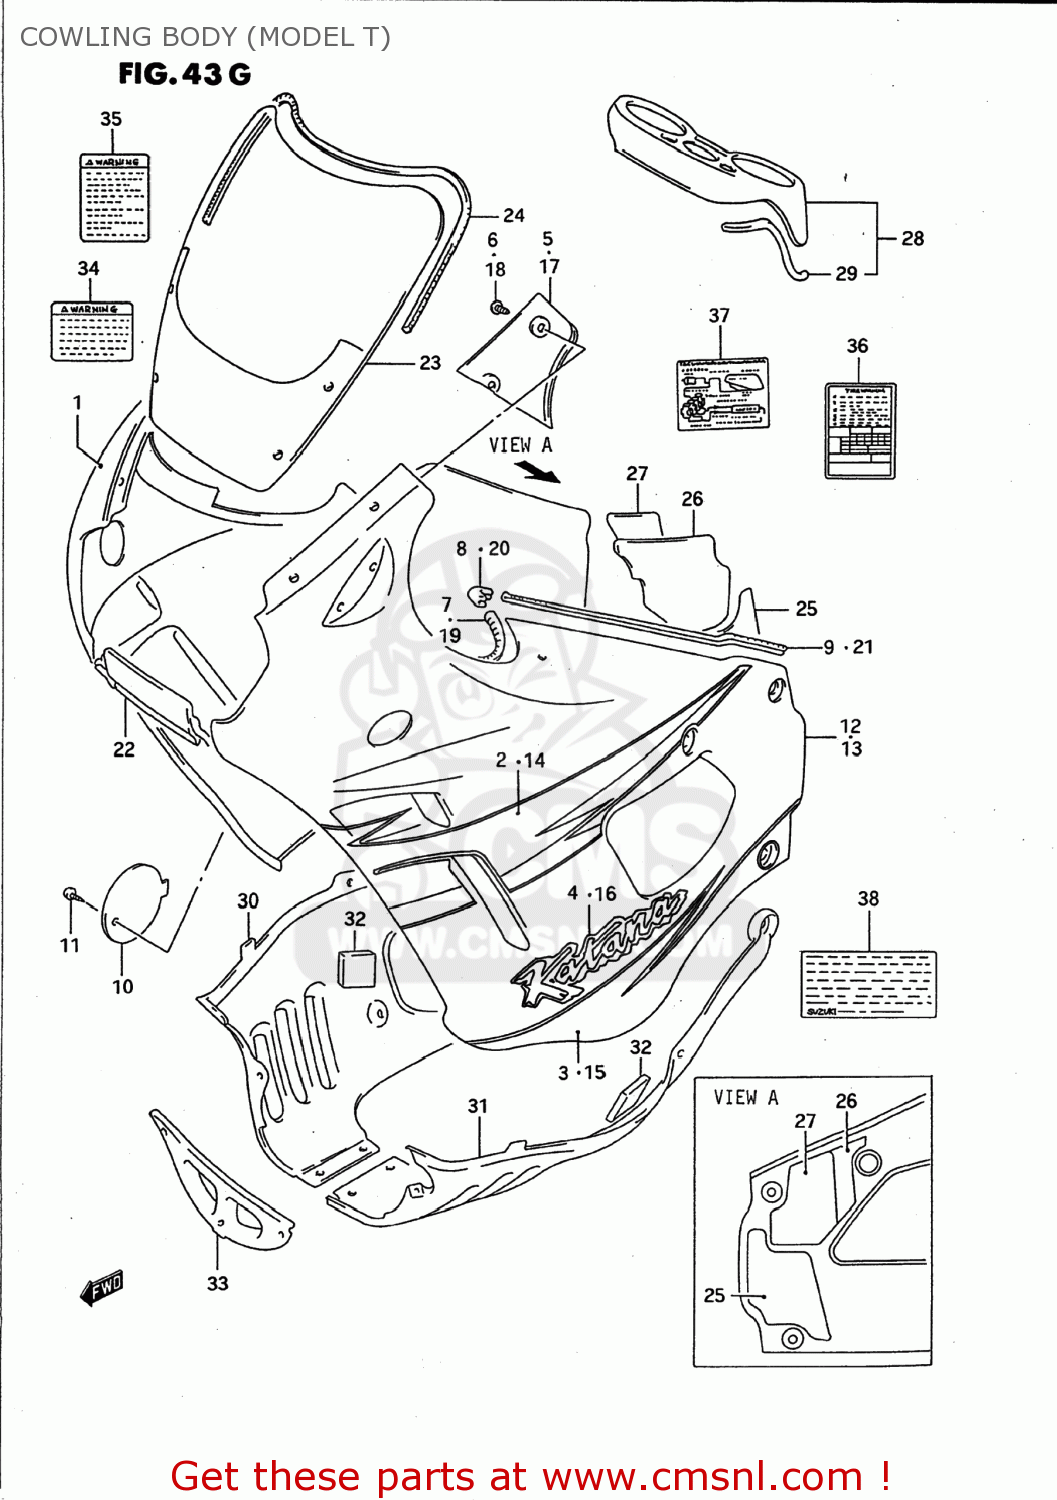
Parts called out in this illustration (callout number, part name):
1	COVER ASSEMBLY,COWLING,RIGHT
2	TAPE,BODY COWL SIDE UPR,R
3	TAPE,BODY COWL SIDE LWR,R
4	EMBLEM,COWLING SIDE
5	COVER,METER SIDE,RIGHT
6	SCREW
7	MOLD,COWLING
8	JOINT,MOLDING END
9	MOLDING
10	LID,OIL
11	SCREW(6X16)
12	COVER ASSEMBLY,COWLING,LEFT
13	COVER ASSEMBLY,COWLING,LEFT
14	TAPE,BODY COWLING SIDE,UPPER
15	TAPE,COWL SIDE,LOWER,LEFT
16	EMBLEM,COWLING SIDE
17	COVER,METER SIDE,L
18	SCREW
19	MOLD,COWLING
20	JOINT,MOLDING END
21	MOLDING
22	PANEL,COWLING CTR
23	WINDSCREEN
24	MOLDING,WINDSCREEN
25	SHEET,COWLING BALANCER
26	BALANCER SHEET,COWLING,R
27	CUSHION,COWLING,R
28	COVER,METER
29	MOLDING,METER COVER
30	COVER,COWLING UNDER,R
31	COVER,COWLING UNDER,L
32	CUSHION,UNDER COWLING
33	COVER,COWLING UNDER FR
34	LABEL
35	LABEL (WARNING SCREEN)
36	LABEL (TIRE AIR PRESSURE)
37	LABEL (VACUUM HOSE ROUTING)
38	LABEL (MANUAL NOTICE)
